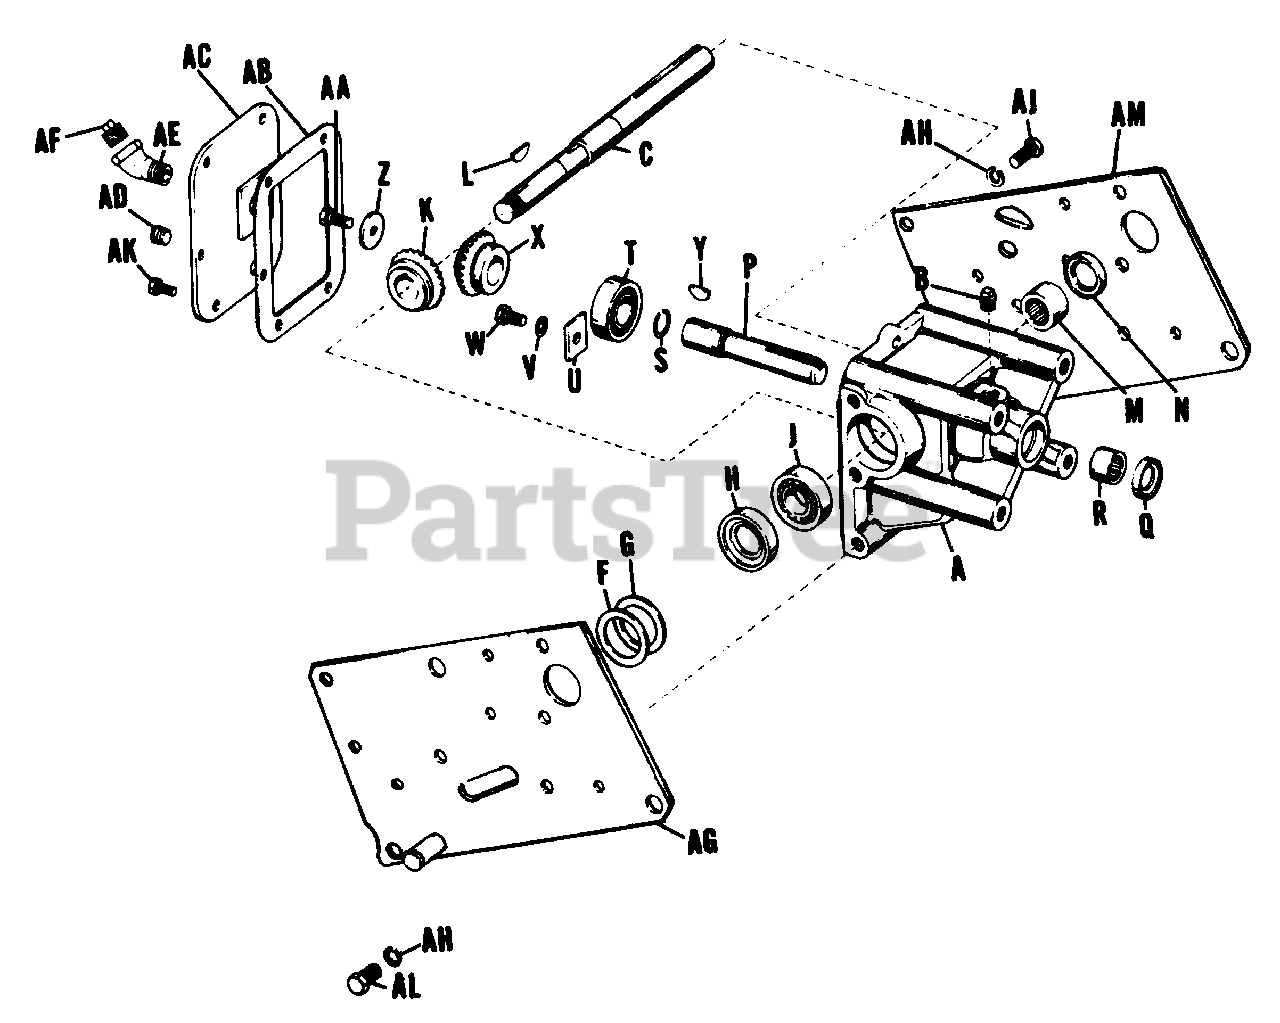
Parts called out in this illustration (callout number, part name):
A	Bevel Gear Housing, W/Bearings
B	Pipe Plug
C	Drive Shaft
E	Hex Jam Nut
F	Shim (As Required)
J	Ball Bearing
K	Bevel Driven Gear
M	Needle Bearing
P	Driven Shaft
R	Needle Bearing
S	Retaining Ring
T	Ball Bearing
U	Bearing Clamp Plate
V	Lock Washer, 5/16"
W	Hex Capscrew, 5/16"-18 x 5/8" lg.
X	Bevel Driven Gear
AA	Hex Capscrew, 5/16"-18 x 3/4" lg.
AC	Housing Cover Assembly
AD	Pipe Plug
AE	Street Elbow
AF	Pipe Plug
AG	R.H. Side Plate
AH	Lock Washer, 7/16"
AJ	Hex Capscrew, 7/16"-14 x 1" lg.
AK	Hex Capscrew 1/4"-20 x 5/8" lg.
AL	Hex Capscrew 7/16"-14 x 1-1/4" lg.
AM	L.H. Side Plate
